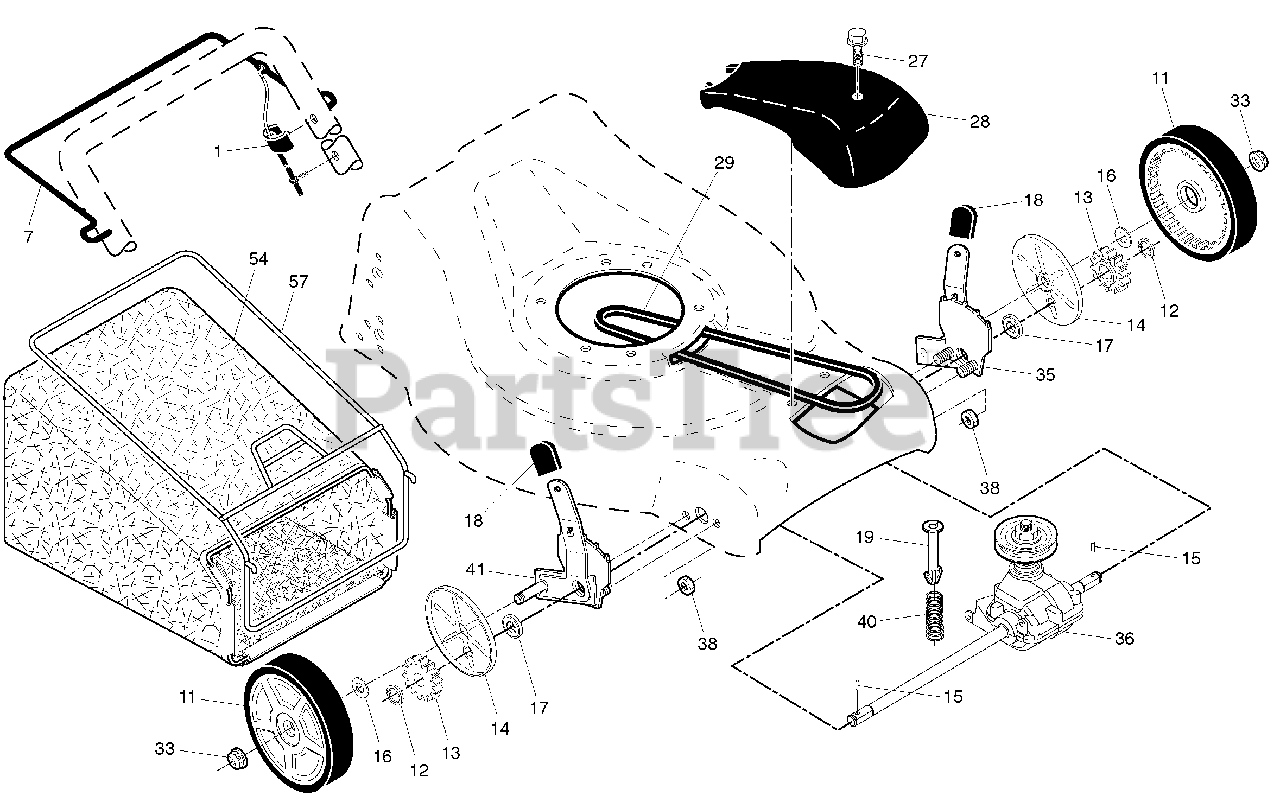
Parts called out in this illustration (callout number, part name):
1	Cable Assembly, Drive Control
6	Spring Retainer
7	Control Bar, Drive
11	Wheel & Tire Assembly
12	E-Ring
13	Pinion
14	Dust Cover
15	Pawl, Drive
16	Washer 1/2 x 1-1/2 x .134
17	Bearing Assembly, Wheel Adjuster
18	Selector Knob
27	Pan Head Tapping Screw #10-24 x 2-3/4
28	Drive Cover
29	V-Belt
33	Locknut, Hex
35	Kit, Wheel Adjuster, LH
36	Gear Case Assembly, Complete
38	Locknut 1/4-20
40	Spring
41	Kit, Wheel Adjuster, RH
54	Grassbag Assembly
57	Frame, Grassbag
